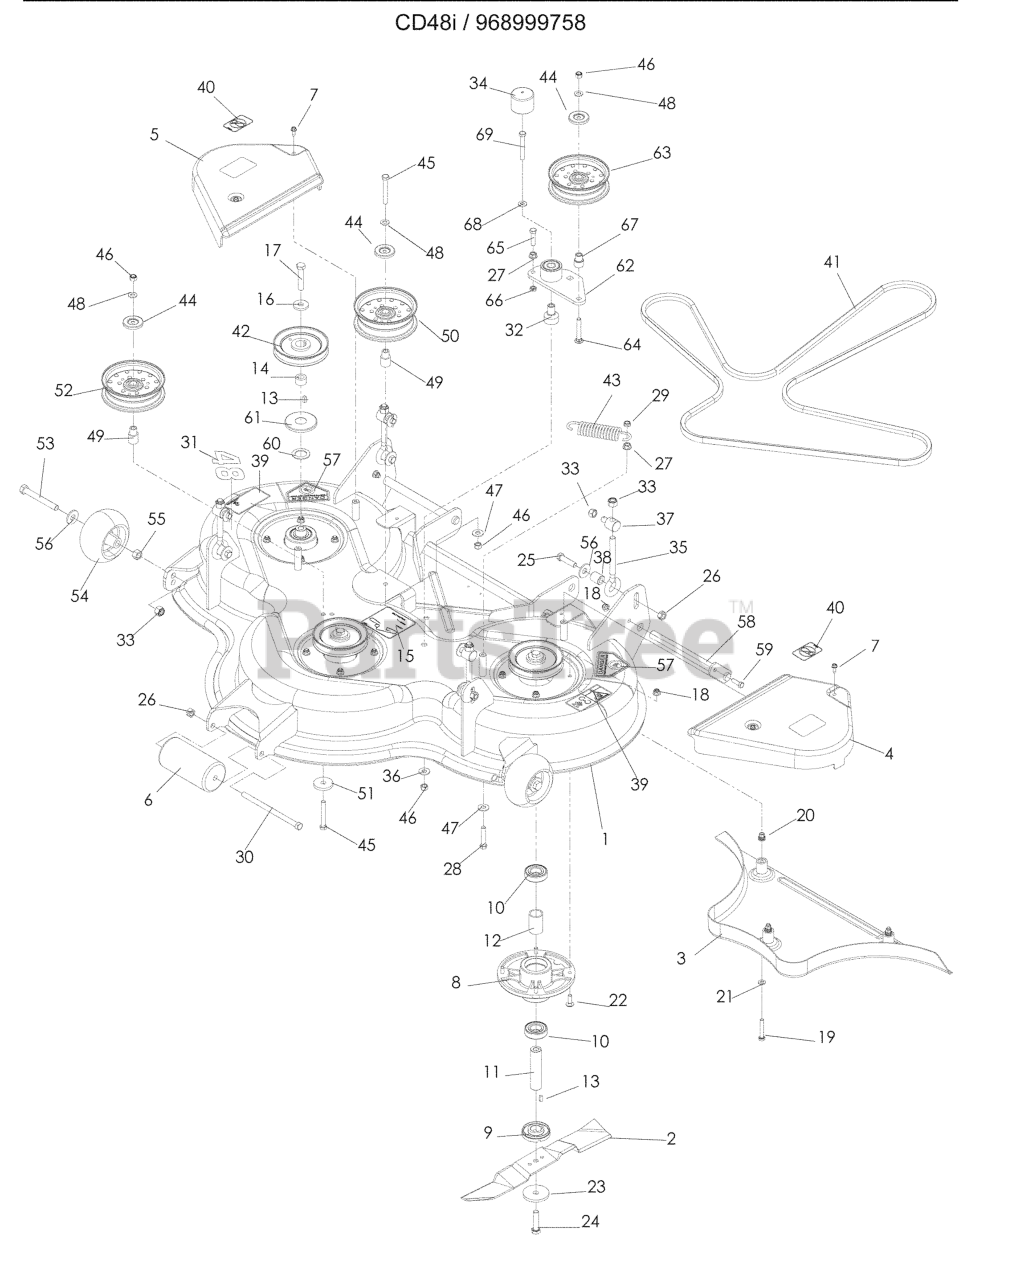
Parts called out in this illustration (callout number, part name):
1	DECK W/DECALS, 48I HUS
2	BLADE
3	PLUG, MULCH, ORANGE
4	BELT SHIELD LT
5	BELT SHIELD RT
6	ROLLER
7	SCREW 1/4 X 5/8
8	BEARING HOUSING
9	BUSHING, BLADE
10	BALL BEARING
14	KEY RETAINER
15	DECAL, BELT ROUTING
16	WASHER-.533IDX1.37OD
17	HCS M12 X 1.75 X 60 GR5 ZD
18	5/16-18 NYLOC FLANGE NUT
19	HCS M8 X 1.25 X 50 GR8.8 ZD
21	FLAT WASHER 5/16 SAE
22	RHSNB 5/16C X 1
24	HCS M12 X 1.75 X 50 GR8.8 ZD
25	HCS 7/16 - 14 X 1 3/4
26	NUT 7/16C CENTERLOCK
27	NUT 3/8C WHIZ
28	HCS 3/8C X 2
29	NUT HEX 3/8-16 NYLON, THIN
30	HCS 7/16-14 X 7 GR5 ZD
32	PIVOT, BEARING
33	NUT 1/2-13 HEX NYLOC ZD
34	CAP, VINYL
36	WASHER, SUPPORT
37	SWIVEL, DECK HEIGHT ADJ
39	DECAL, BELT DRIVE
40	DECAL, NO STEP
41	BELT, DECK
42	PULLEY, 48
44	SHIELD, DUST
45	SCREW 3/8C X 2 3/4 HEX CAP
46	NUT 3/8-16 NYLOC
47	WASHER 3/8 FLAT
48	WASHER, 3/8 THICK
49	IDLER BUSHING
50	IDLER PULLEY (TALL)
51	SPINDLE WASHER
52	IDLER PULLEY
53	HCS 1/2-13 X 4 GR 5 ZD
54	GAUGE WHEEL
55	NUT HEX 1/2
56	WASH USS FLAT 1/2
57	DECAL, CPSC
59	HCS 5/16C X 1
60	WASHER-1.06IDX1.63ODX.06
61	BOTTOM DUST CAP
62	ARM-IDLER W/BRG
63	IDLER PULLEY
64	CARRIAGE BOLT 3/8-16 X
65	HCS 3/8-16 X 1-1/2
66	NUT 3/8-16 HEX JAM
67	BUSHING, IDLER
68	CONTACT BELLSPR 1/2
69	SCREW, 1/2C X 3 HEX CAP
